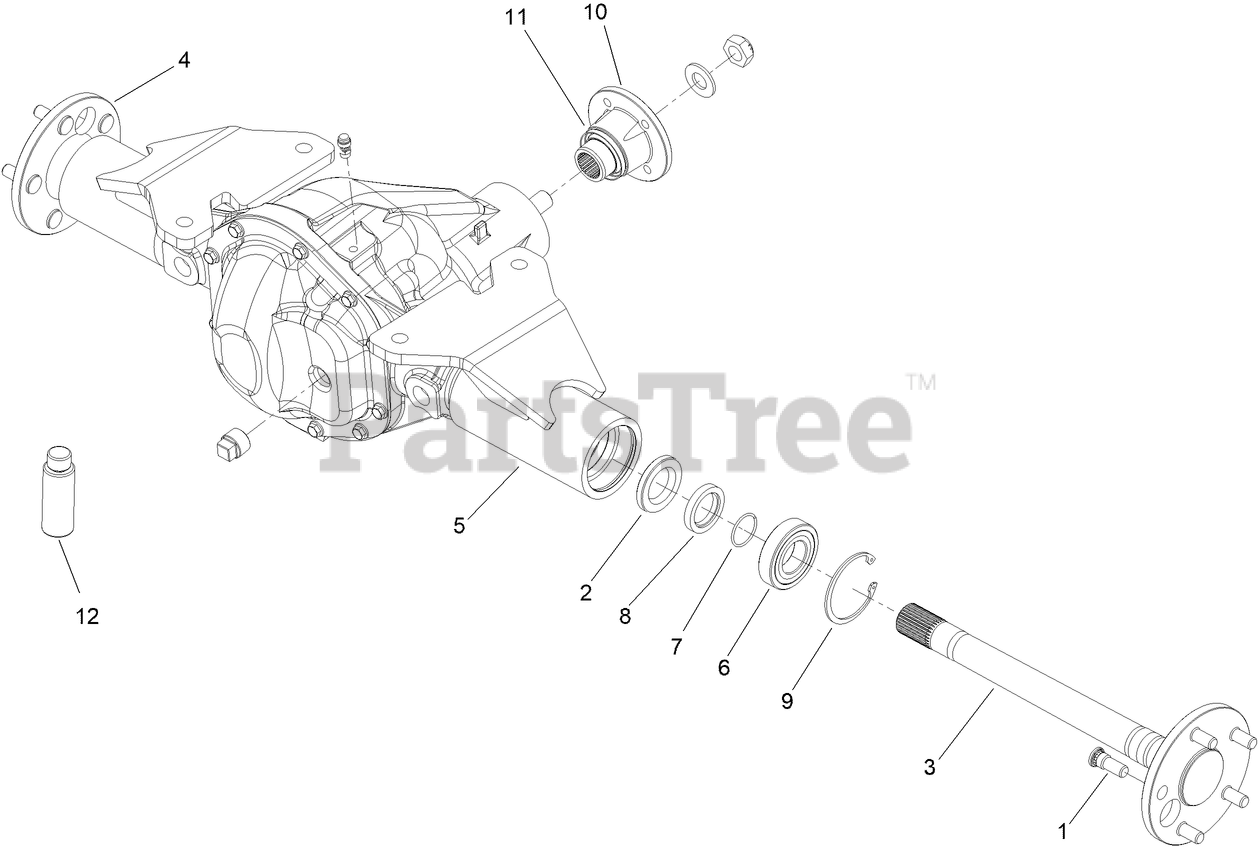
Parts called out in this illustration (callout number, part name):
1	LUG BOLT (1/2-NF X 1-1/2")
2	INTERNAL SEAL
3	AXLE LONG - DANA 44
4	AXLE - SHORT DANA 44
5	DIFFERENTIAL - DANA 44
6	BALL BEARING-SEALED (1.378")
7	EXTERNAL SNAP RING (1.380")
8	AXLE RING
9	INTERNAL SNAP RING
10	DIFFERENTIAL FLANGE
11	SLINGER
12	FRICTION MODIFIER (DANA-SPICER)
